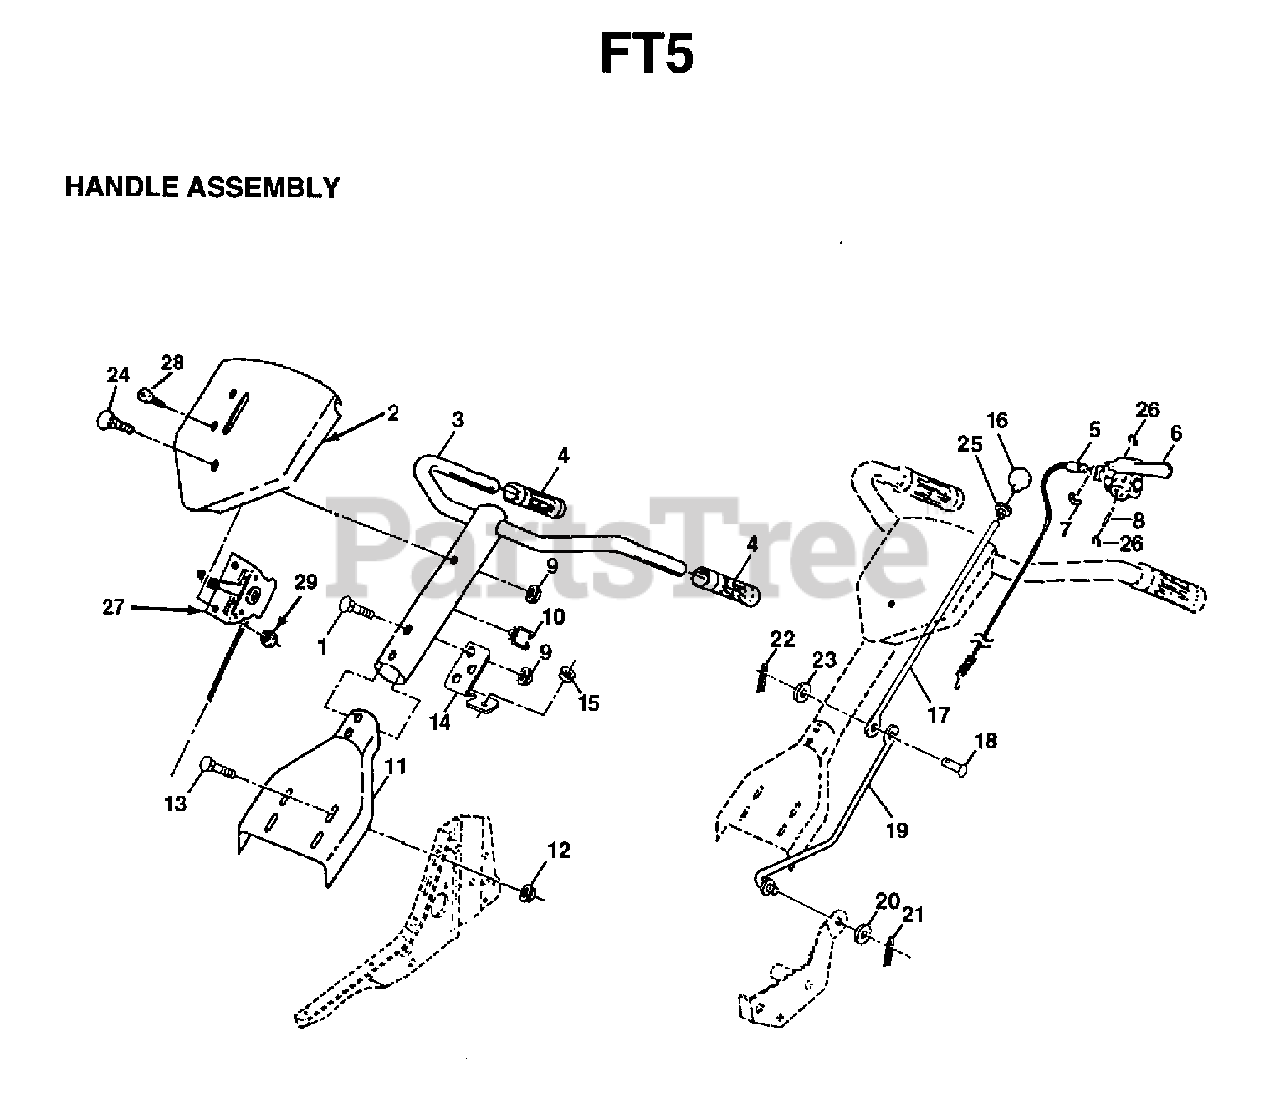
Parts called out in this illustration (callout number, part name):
1	BOLT.5/16-18X2.5
7	RETAINING RING
12	NUT
13	BOLT.RH.SQNK.5/16
16	KNOB T (3/8 HOLE)
21	COTTER PIN
22	COTTER PIN
24	BOLT.5/16-18X2.5
26	RETAINING RING
28	SCREW.PNHD.10-24
29	NUT **
